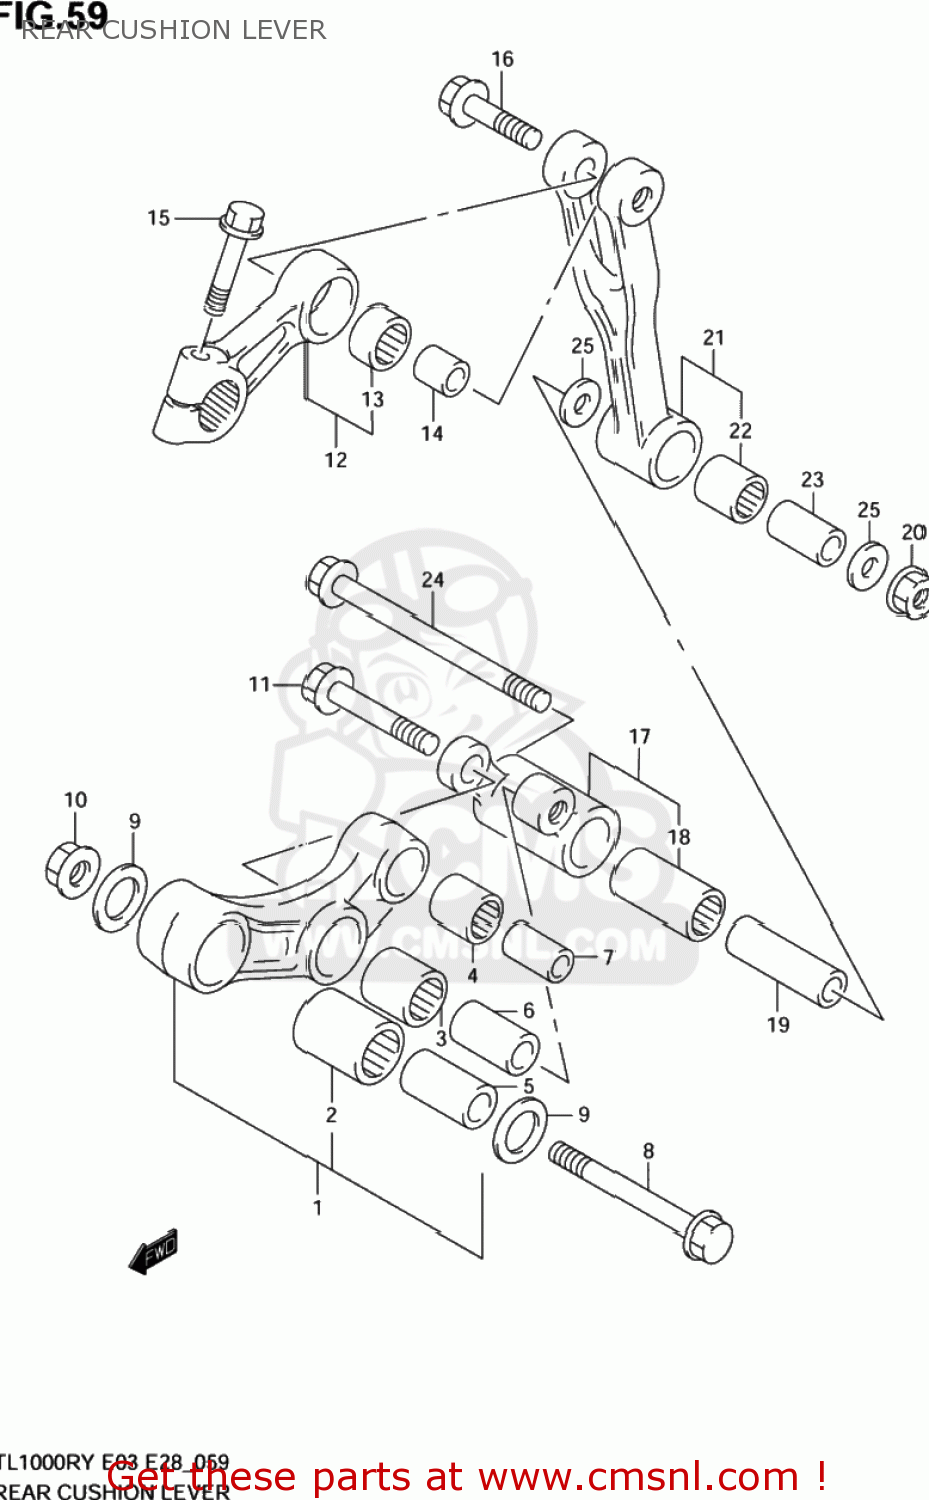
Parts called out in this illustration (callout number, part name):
1	LEVER SET,RR CUSHION
2	BEARING(20X27X32)
3	BEARING(20X27X32)
4	BEARING(17X24X26)
5	SPACER,RR CUSHION LEVER FR
6	SPACER,RR CUSHION LEVER FR
7	SPACER,RR CUSHION LEVER
8	BOLT,RR CUSHION LEVER FR
9	SHIM(20X30X0.5)
10	NUT 12MM
11	BOLT,CUSHION LEVER FR
12	ARM SET,REAR CUSHION
13	BEARING(17X25X16.7)
14	SPACER,RR CUSH ARM
15	BOLT(8X31)
16	BOLT(10X40)
17	ROD SET,RR CUSHION,R
18	BEARING(20X27X23.5)
19	SPACER,RR CUSHION ROD,R
20	NUT 12MM
21	ROD SET,RR CUSHION,L
22	BEARING(20X27X26)
23	SPACER,RR CUSHION LEVER FR
24	BOLT,CUSHION ROD
25	SHIM(20X28X1.5)
